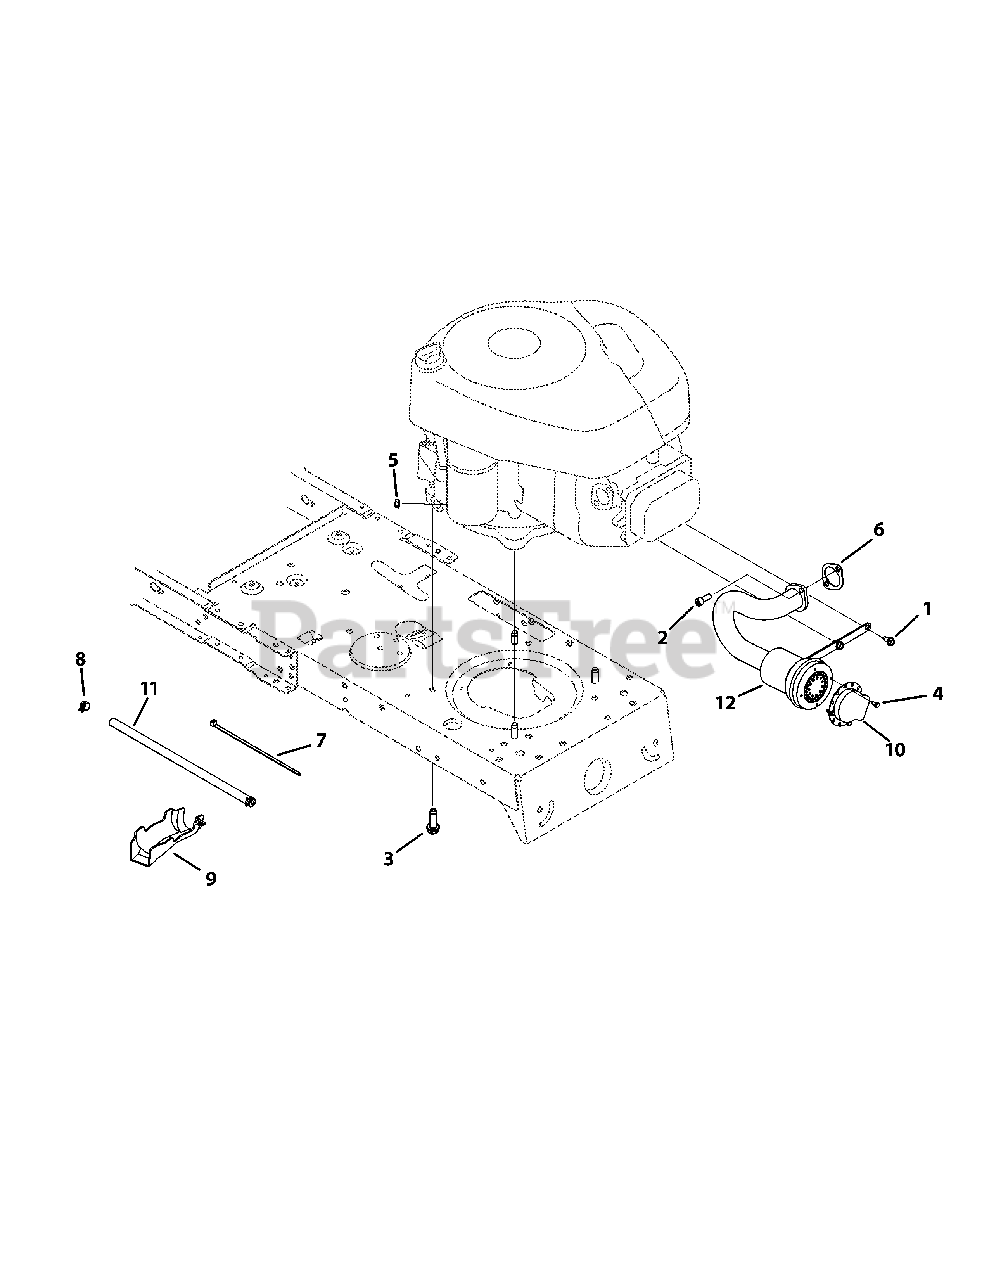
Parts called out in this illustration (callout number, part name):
1	Screw, 1/4-20 x .500
2	Socket Screw, 5/16-18 x .750
3	Screw, 3/8-16 x 1.0
4	Screw, 8-18 x .500
5	Sems Nut, 1/4-20
6	Exhaust Gasket
7	Cable Tie
8	Clamp Hose, .490 diameter
9	Oil Drain Sleeve
10	Muffler Deflector
11	Fuel Hose, Low Permeation
12	Muffler
